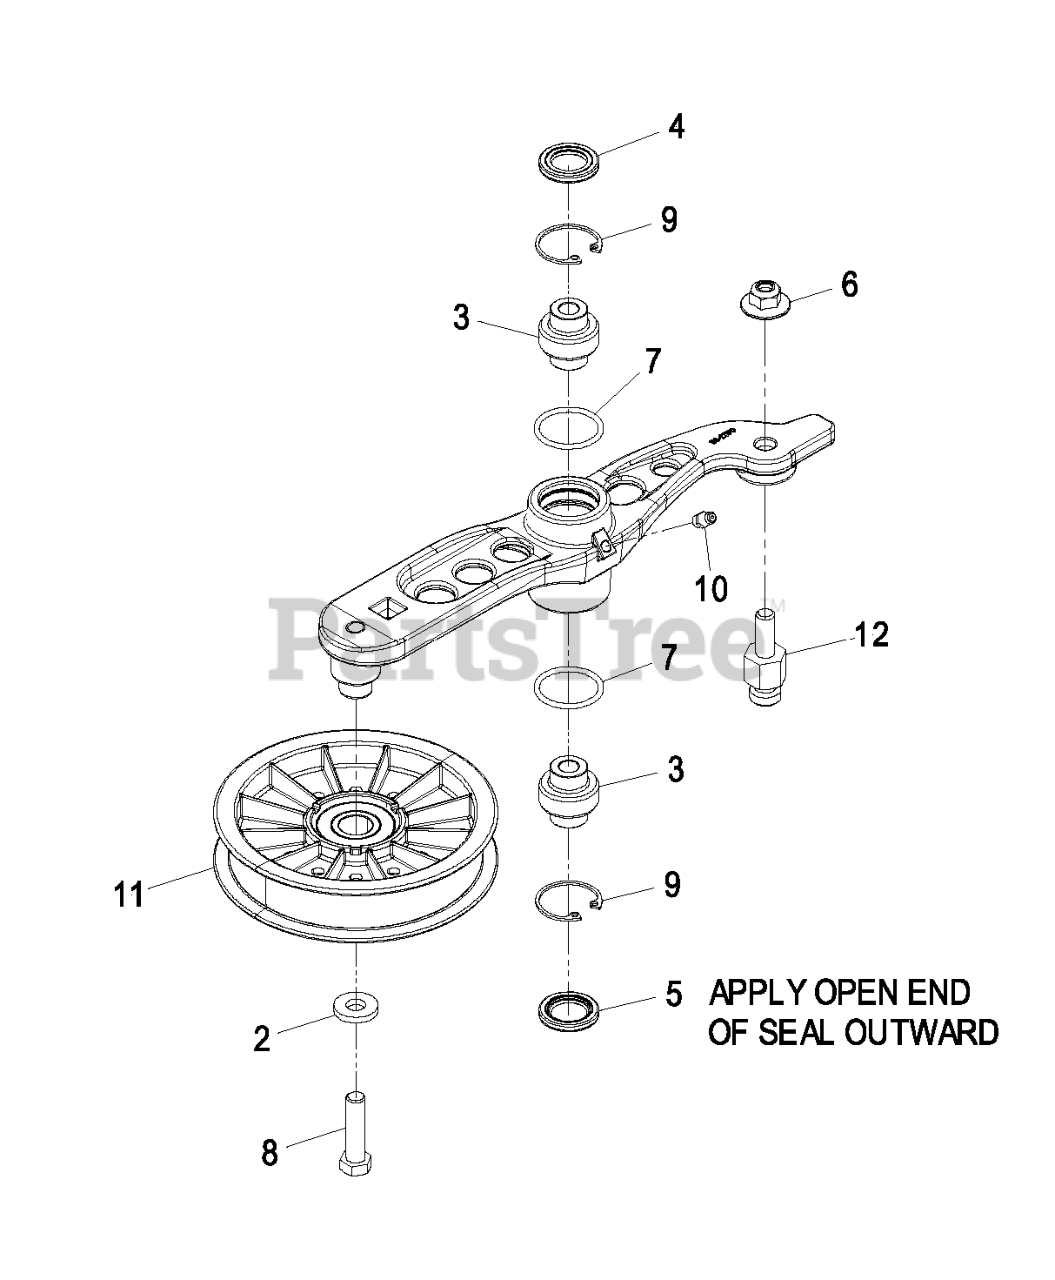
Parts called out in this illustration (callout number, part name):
3	BEARING-SPHERICAL
4	SEAL-LIP, DOUBLE
5	SEAL-LIP, SINGLE
6	Nut-Nyloc 3/8-16 Flg
8	SCREW-HH
9	RING-SNAP
10	FITTING-GREASE
11	PULLEY-IDLER
